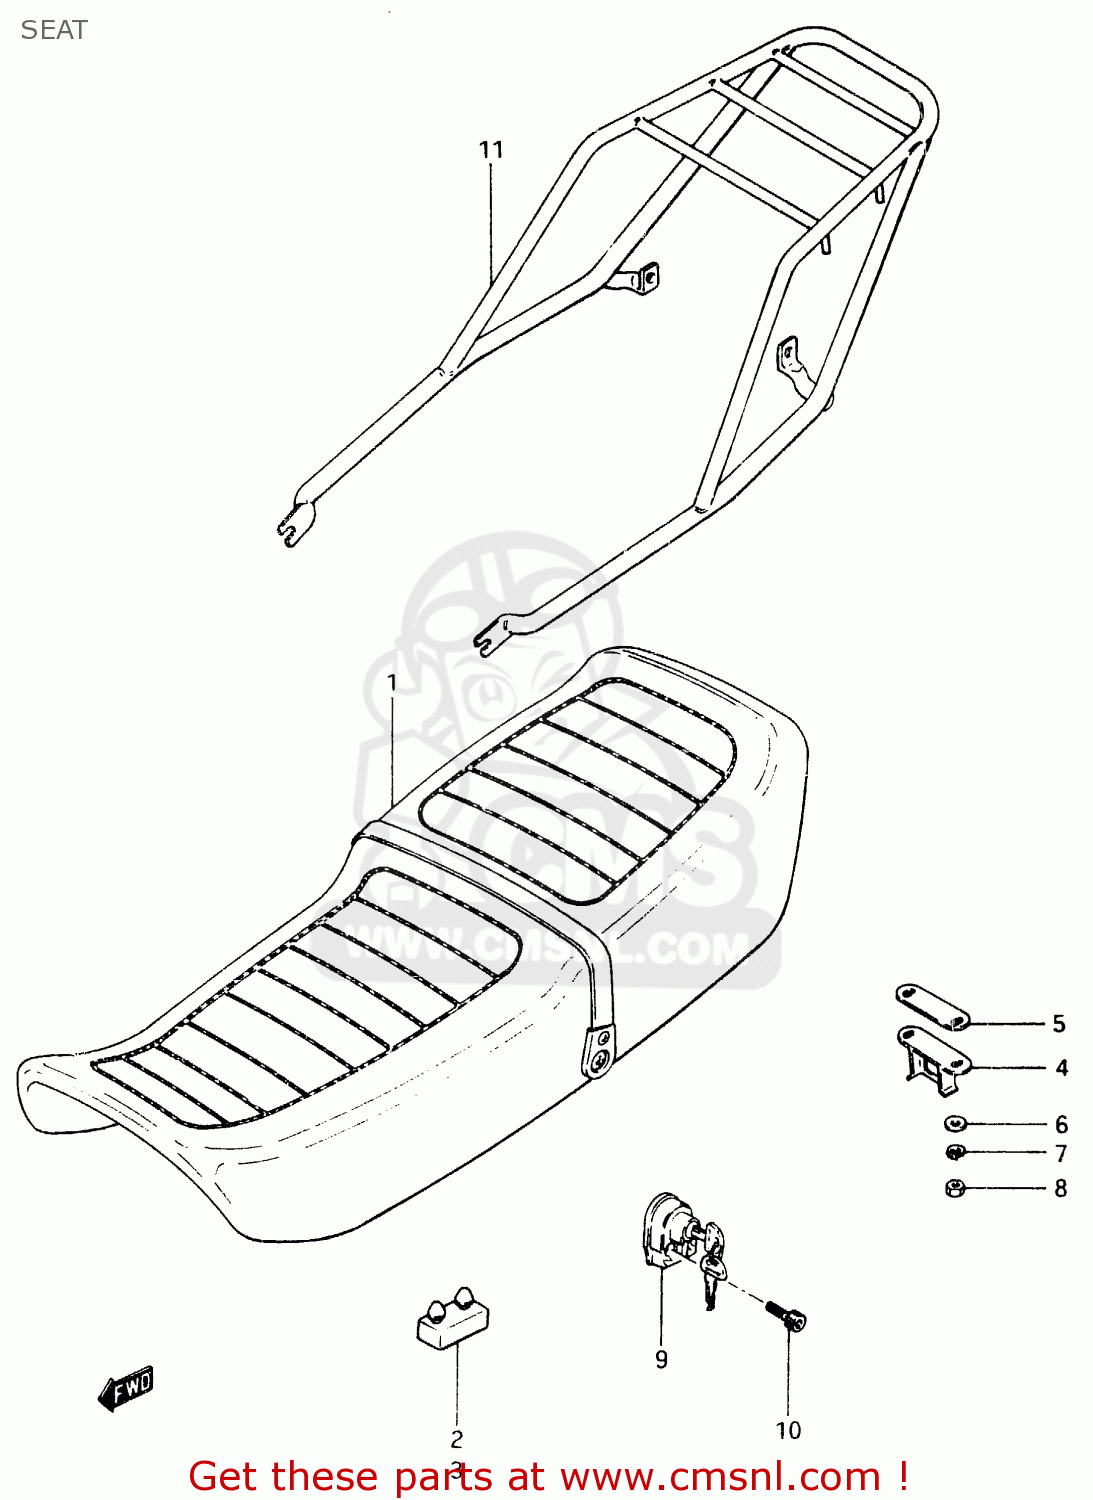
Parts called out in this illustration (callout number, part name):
1	SEAT ASSY (BLACK)
2	CUSHION
3	CUSHION
4	STRIKER, SEAT LOCK
5	SHIM,SEAT LOCK STRIKER
6	WASHER
7	LOCK WASHER
8	NUT 6MM
9	LOCK ASSY,HELMET
10	BOLT 5X25
11	CARRIER, SPORTS
